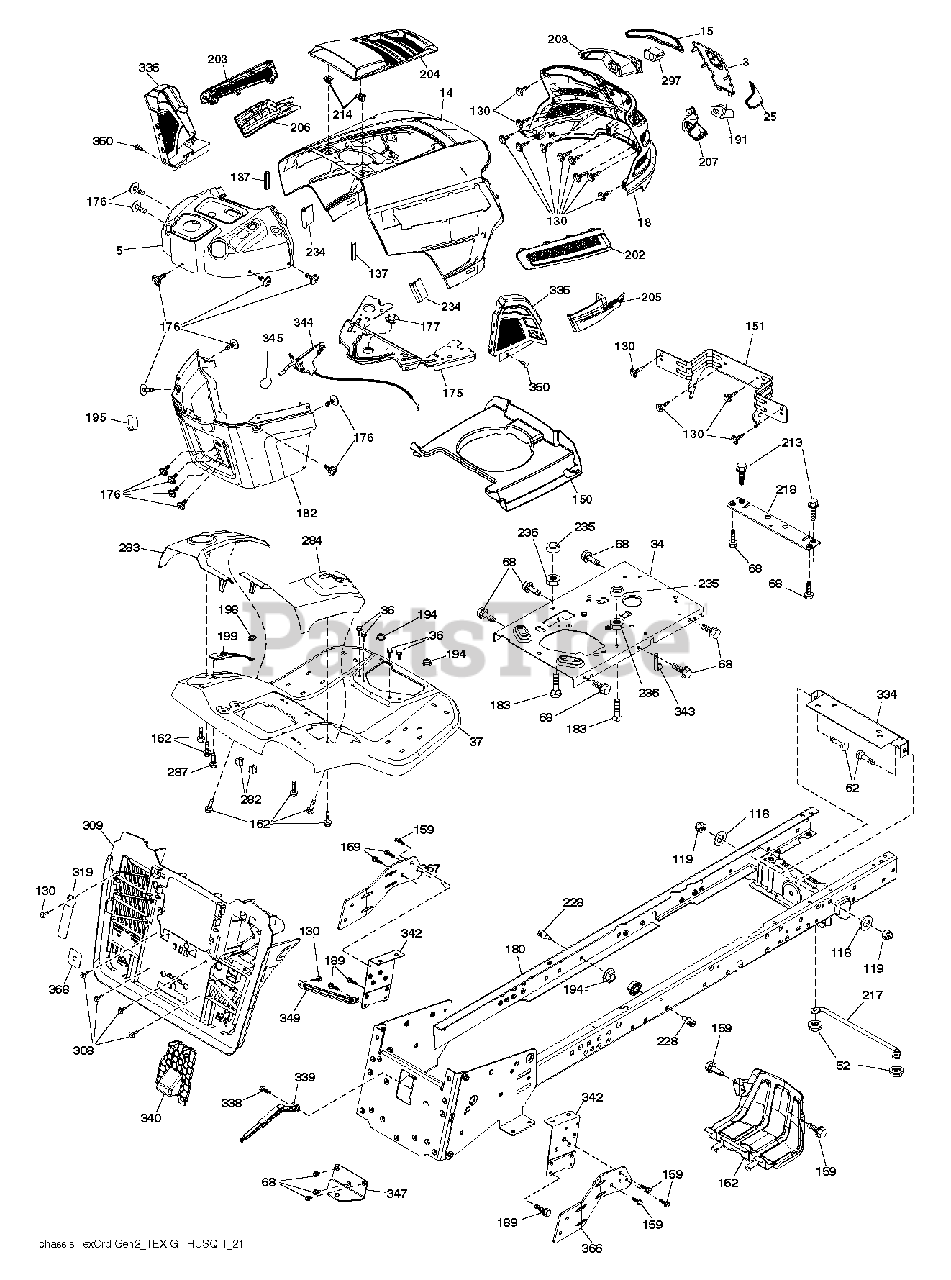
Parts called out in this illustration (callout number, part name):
3	APPLIQUE.SUBASM.GT.HUSQ.II
5	UPPER.GT2.SVC.MINDING.PTO.H.
14	HOOD.ASM.HUSQVARNA.GT.TEX.ORAN
15	LENS.HEADLIGHT.LH.GTII.2011
18	GRILLE.SUBSTRATE.2011.
25	LENS.HEADLIGHT.RH.GTII.2011
34	PLATE.ENGINE.10GA.CRD.GENII
36	SCREW 5/16"
37	FENDER.TEX.SRD.CRD.BASE
52	LOCKNUT
62	BOLT D
68	SCREW LT
118	WASHER
130	SCREW.#10 X 0.750.BOS
137	BUMPER DASH
150	AIR.DUCT.GTV.BLACK
151	BRACKET.PIVOT.HOOD.GT.HUSQ.II
152	SHIELD.BROWNING.PNT.GT.V2
159	SCREW, 3/8-16X3/4
162	SCREW.HI-LO.CONSOLE
175	PLATE.CROSSMEMBER.HUSQ
176	SCREW.#10-24X5/8.RN.QU
177	BUSHING STEERING
180	WELDMENT.CHASSIS.TEX.CRD.GEN.2
182	DASH DASH LOWER
183	BOLT.5/16-18X1-1/4 FULL THD
189	SCREW
191	INSERT.REFLECTIVE.RH.HUSQ.GTII
194	NUT LOCK HEX FLANGE 5/16-18
195	PLUG.HOLE.DASH.LOWER.12V.BLK
198	INDICATOR.DECK.LIFT.RED
199	PLATE DECK LIFT
202	VENT.SIDE.RH.GT.HUSQ.II.
203	VENT.SIDE.LH.GT.HUSQ.II.498
204	VENT.TOP.HUSQ.GT2
205	SIDE.TRIM.RH.GT.HUSQ.II
206	SIDE.TRIM.LH.GT.HUSQ.II.GRAY
207	BEZEL LIGHT.RH.GT.II.MYLAR
208	BEZEL LIGHT.LH.GT.II.MYLAR
213	BOLT
214	CLIP.RETAINER.TINNER.
217	ROD.PIVOT.HOOD
218	X-PIECE.HOOD.STOP.NON/
228	STUD.FASTNER.W/ANTI-ROTATE
234	BUMPER.HOOD.TEX.HUSQVARNA
235	SPACER FENDER
236	NUT.CENTERLOCK.5/16-
282	CLIP.RETAINER.CONSOLE.LT.HUSQ
283	CONSOLE.DECKLIFT.CRDII.498
284	CONSOLE.PEDAL.HYDRO
287	SCREW 1/4X20
297	INSERT.REFLECTIVE.LH.HUSQ.GTII
308	BOLT, 5/16-18 X 1 3/4
309	BACKPLATE.ASM.TEX.CRD.GEN2.1
319	LEVER.BAG.CRDII.ANTIROTATION
334	BRACKET.ENGINE
335	COVER.LOWER.DASH.RH.BLACK
336	COVER-LH.LOWER.DASH.GT2.BLACK
338	BOLT BOLT SHOULDER
339	LEVER LEVER BAGGER
340	BATTERY.DOOR.TEX.CRD.GEN.2,1
342	SUPPORT SUPPORT FENDER
343	CLIP CLIP
344	CONTROL.EZ.MULCH.TEX/CRD
345	RP KNOB.OVAL.TAPERED.3/8-16BLK
347	HITCH HITCH TOW TEX CRD GEN 2
349	BRACKET.SUPPORT.LRVB/CRD
350	CLIP.X-MAS.TREE
366	BRACKET.RH.FRONT.BAGGER.BLACK
367	BRACKET.LH.FRONT.BAGGER.BLACK
368	FULL.LEVER.BAGGER.TEX.CRD
